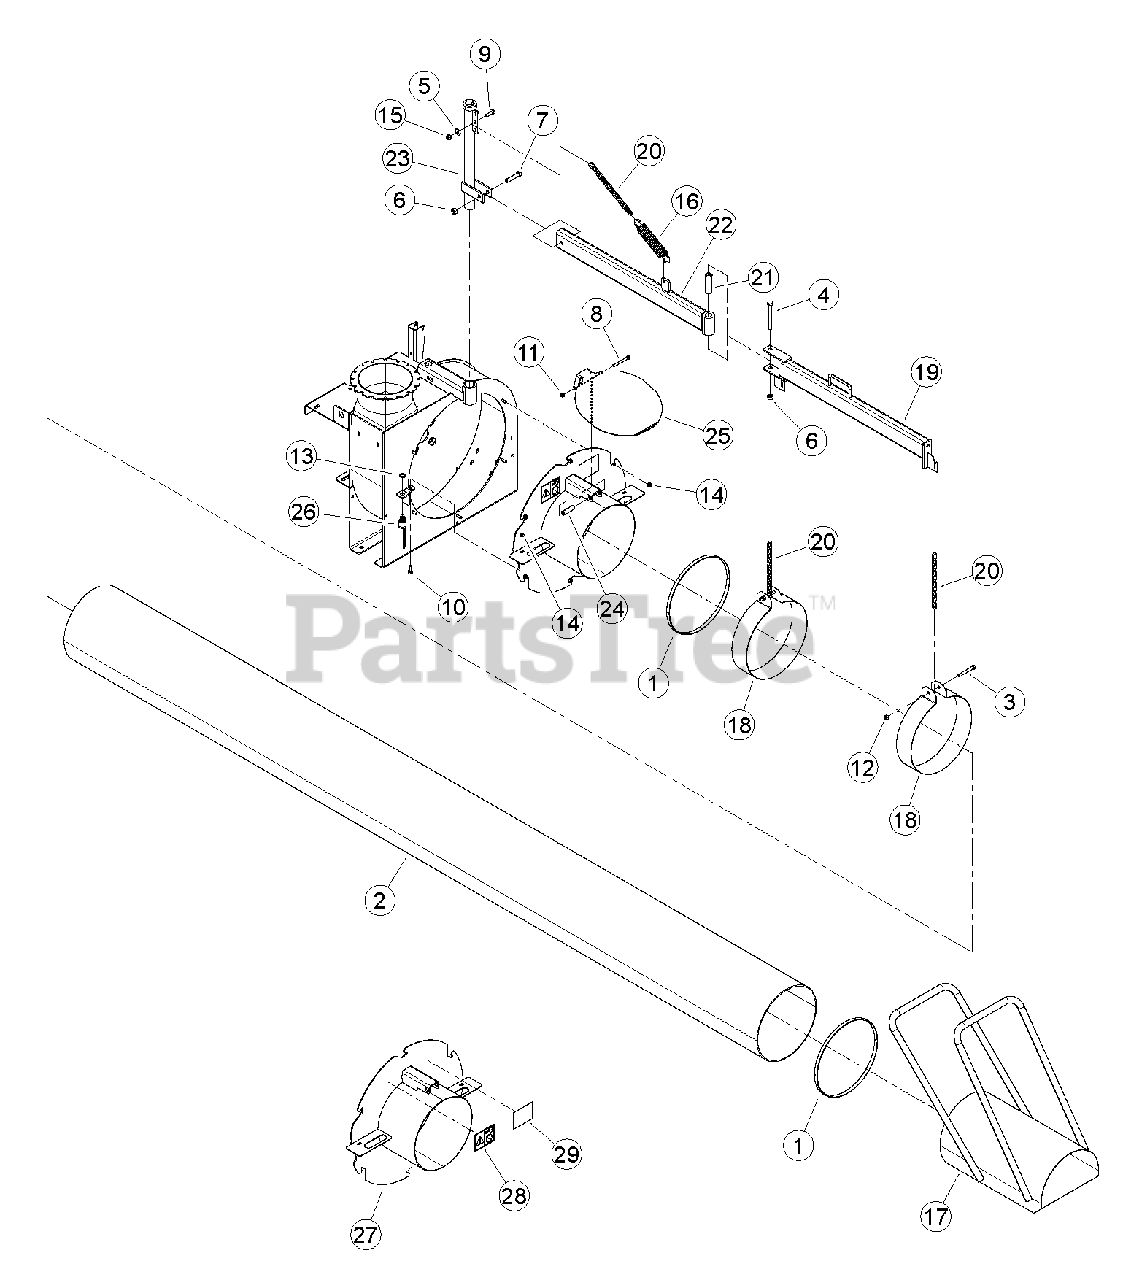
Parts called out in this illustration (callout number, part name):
1	CLAMP, 12 INCH HOSE
2	HOSE, 12 INCH X 12-1/2 FT
3	BOLT, 3/8-16 X 3 GR5 HEX CAPSCREW
4	BOLT, 1/2 X 4-1/2" GR5 HHCS NC ZP
5	WASHER, 3/8 FLAT
6	NUT, 1/2-13 GR5 CENTERLOCK GRB
7	BOLT, 1/2 X 2-1/2 GR5 HEX CAP ZP
8	BOLT, 5/16 X 3 GR5 HEX CAP ZP
9	BOLT, 3/8 X 1-1/4 FLANGE NC
10	BOLT, 5/16 X 1 FLANGE NC
11	NUT, 5/16-18 NE NYLOCK
12	NUT, 3/8-16 NE NYLOCK
13	NUT, 5/8-32 JAM
14	NUT, 5/16-18 NYLOCK FLANGE
15	NUT, 3/8-16 NYLOCK FLANGE
16	SPRING, 7-3/4" EXTENSION
17	WELDMENT, HOSE INLET
18	WRAP, VACUUM HOSE
19	WELDMENT, END ARM
20	CHAIN, HOSE SUPPORT
21	SPACER, TUBE 1 OD X .5 ID X 3.13
22	WELDMENT, HOSE SUPPORT
23	WELDMENT, HOSE SUPPORT
24	SPACER, 5/8 OD X 11 GA X 2.13
25	SHIELD, INTAKE
26	ASSEMBLY, SEALED SWITCH
27	ASSEMBLY, VACUUM INTAKE COVER
28	DECAL, INSTRUCTION ISO
29	DECAL, INSTRUCTION ISO
